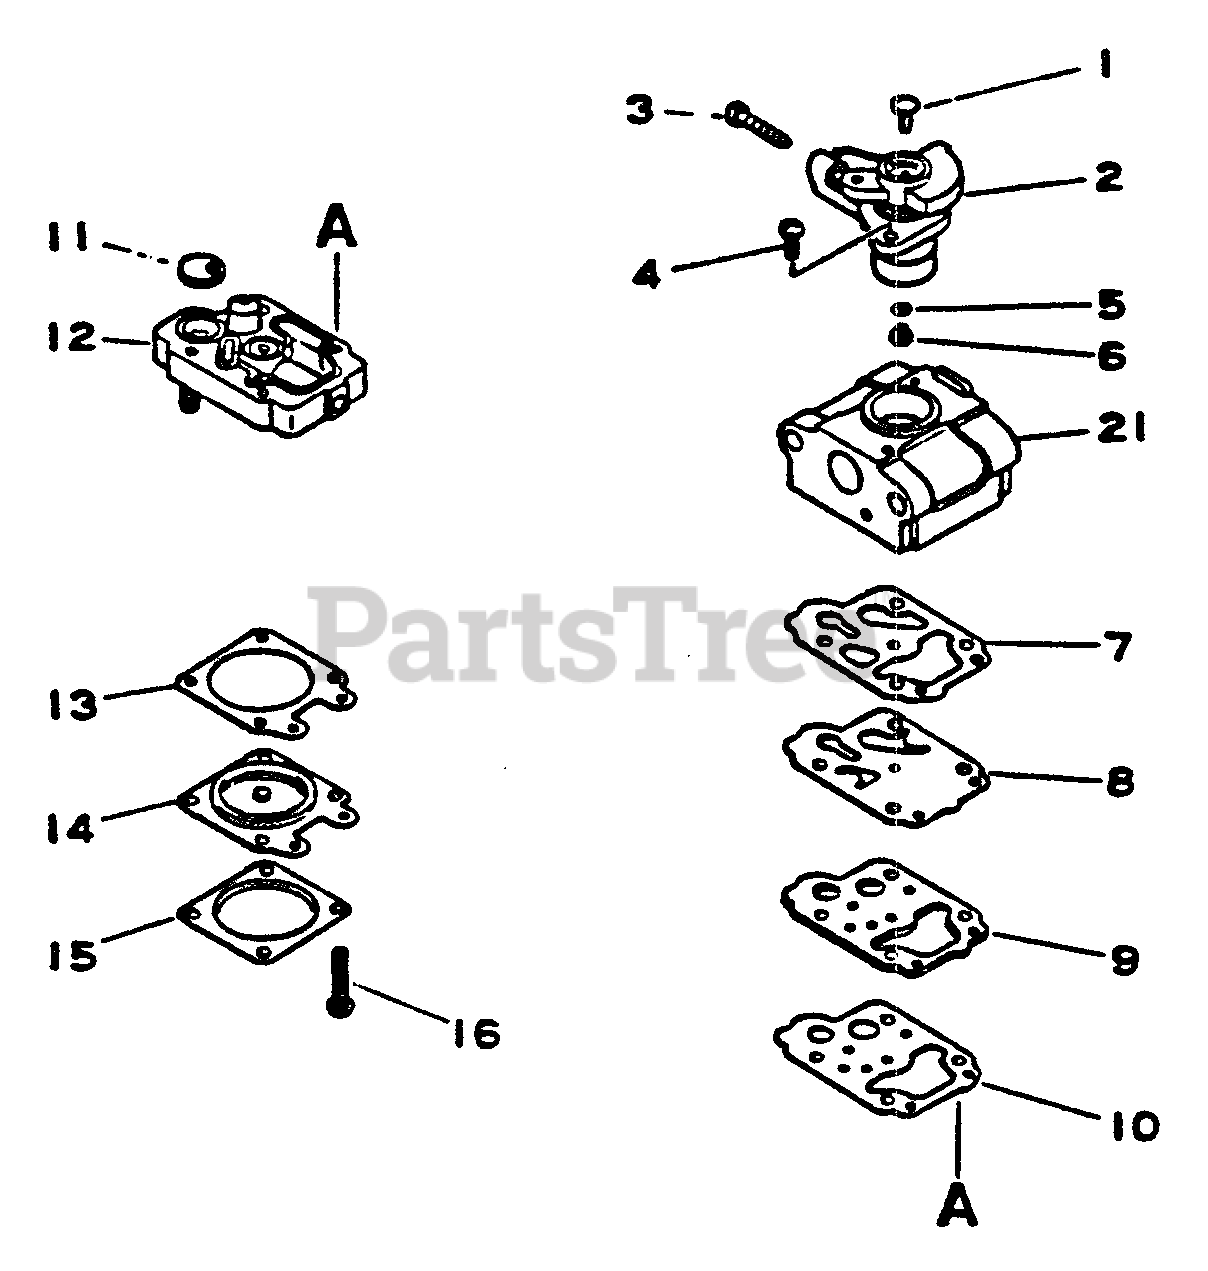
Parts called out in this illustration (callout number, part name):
2	VALVE ASSY, THROTTLE
4	SCREW, THROTTLE COLLAR
5	O-RING
6	JET
7	GASKET, PUMP
8	DIAPHRAGM, PUMP
9	COVER, PUMP
10	GASKET, PLATE
11	STRAINER
12	PUMP BODY ASSY
13	GASKET, DIAPHRAGM
14	DIAPHRAGM, METERING
15	COVER, METERING DIAPHRAGM
16	O-RING 15
16	GASKET, INTAKE
